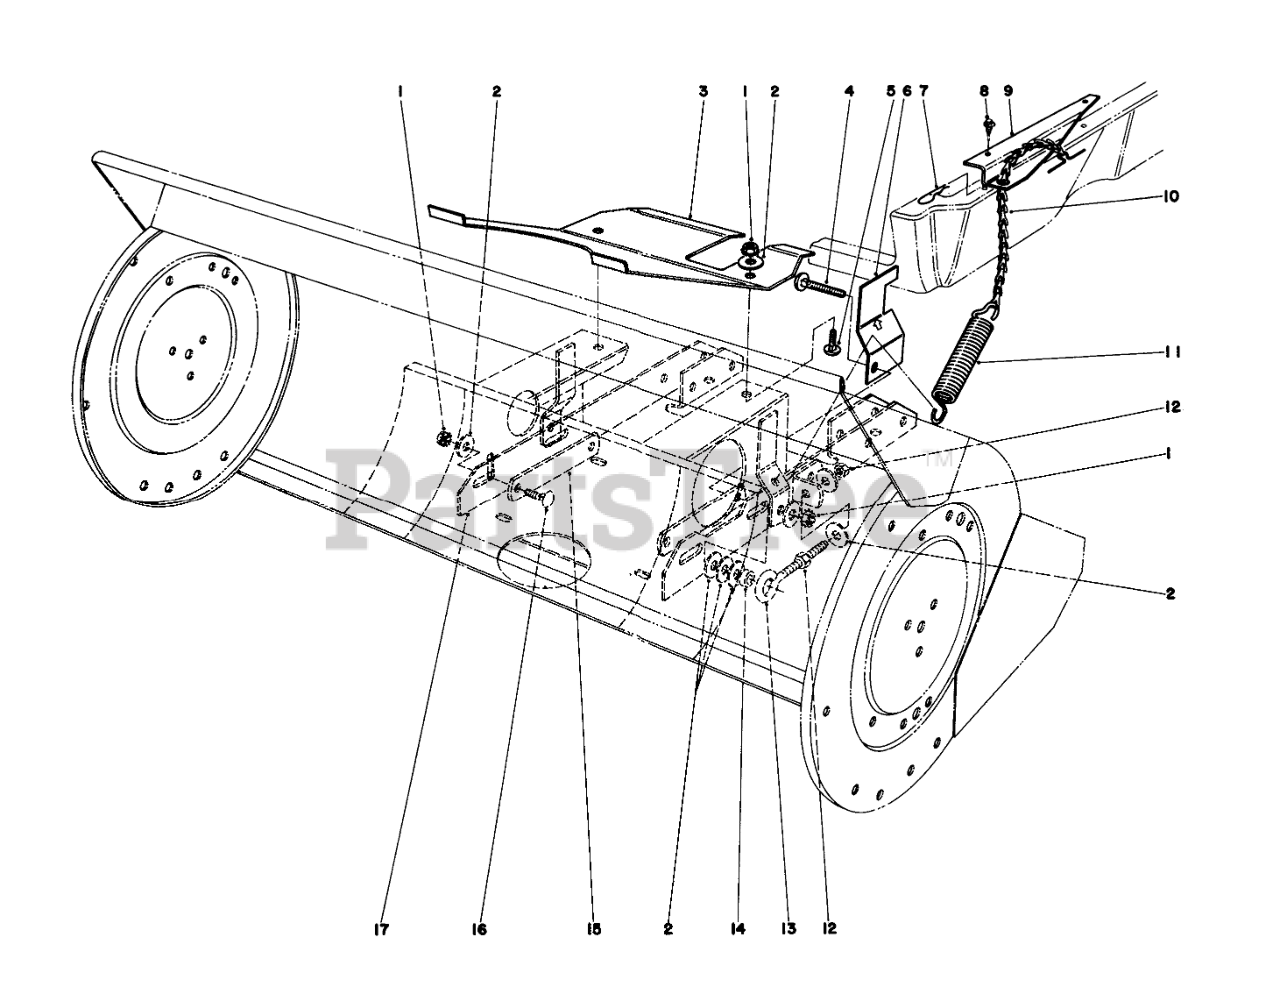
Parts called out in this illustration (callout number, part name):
1	NUT-KEPS
2	WASHER-FLAT
3	Guard-Drive Pulley
4	SCREW-CARR
5	SCREW-CARR
6	Bracket-Belt Adjust Guide
7	PIN-HAIR
8	SCREW-HWHTF
9	Plate-Lift Spring Anchor
10	CHAIN & TOGGLE ASM
11	IDLER ARM SPRING
12	NUT-HEX
13	Eye Bolt
14	Spacer
15	Strap-Header Channel
16	BOLT-CARR
17	Pivot Bracket
